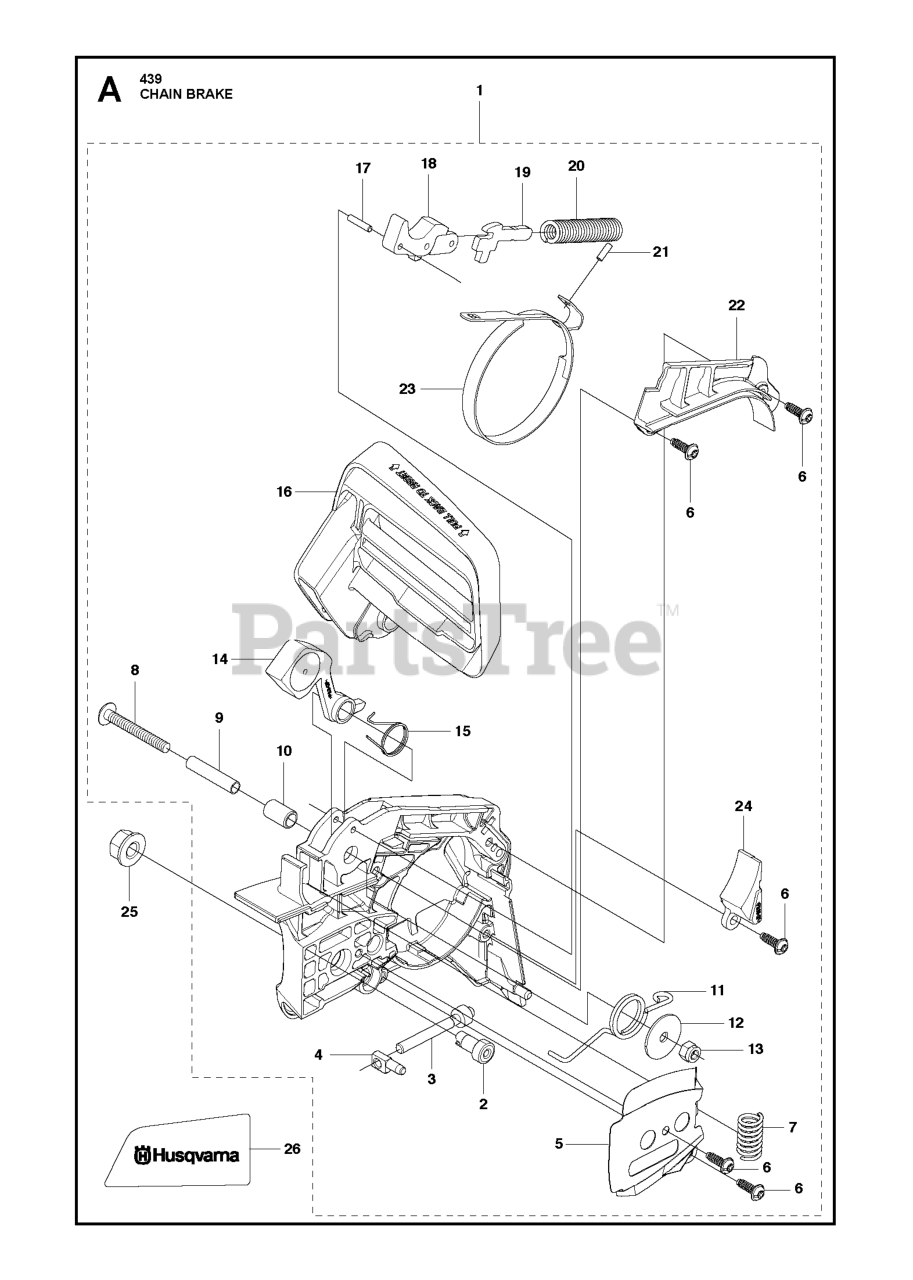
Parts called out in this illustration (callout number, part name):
1	CLUTCH COVER ASSY 439
6	SCREW
8	SCREW
9	SPACER, INNER
11	RETURN SPRING
12	WASHER
15	SPRING
16	HAND GUARD 439
17	ROLLER
18	BRAKE LEVER
19	ARM
20	SPRING
21	ROLLER
22	COVER LID GRAY
23	BRAKE BAND
25	NUT FLANGE
